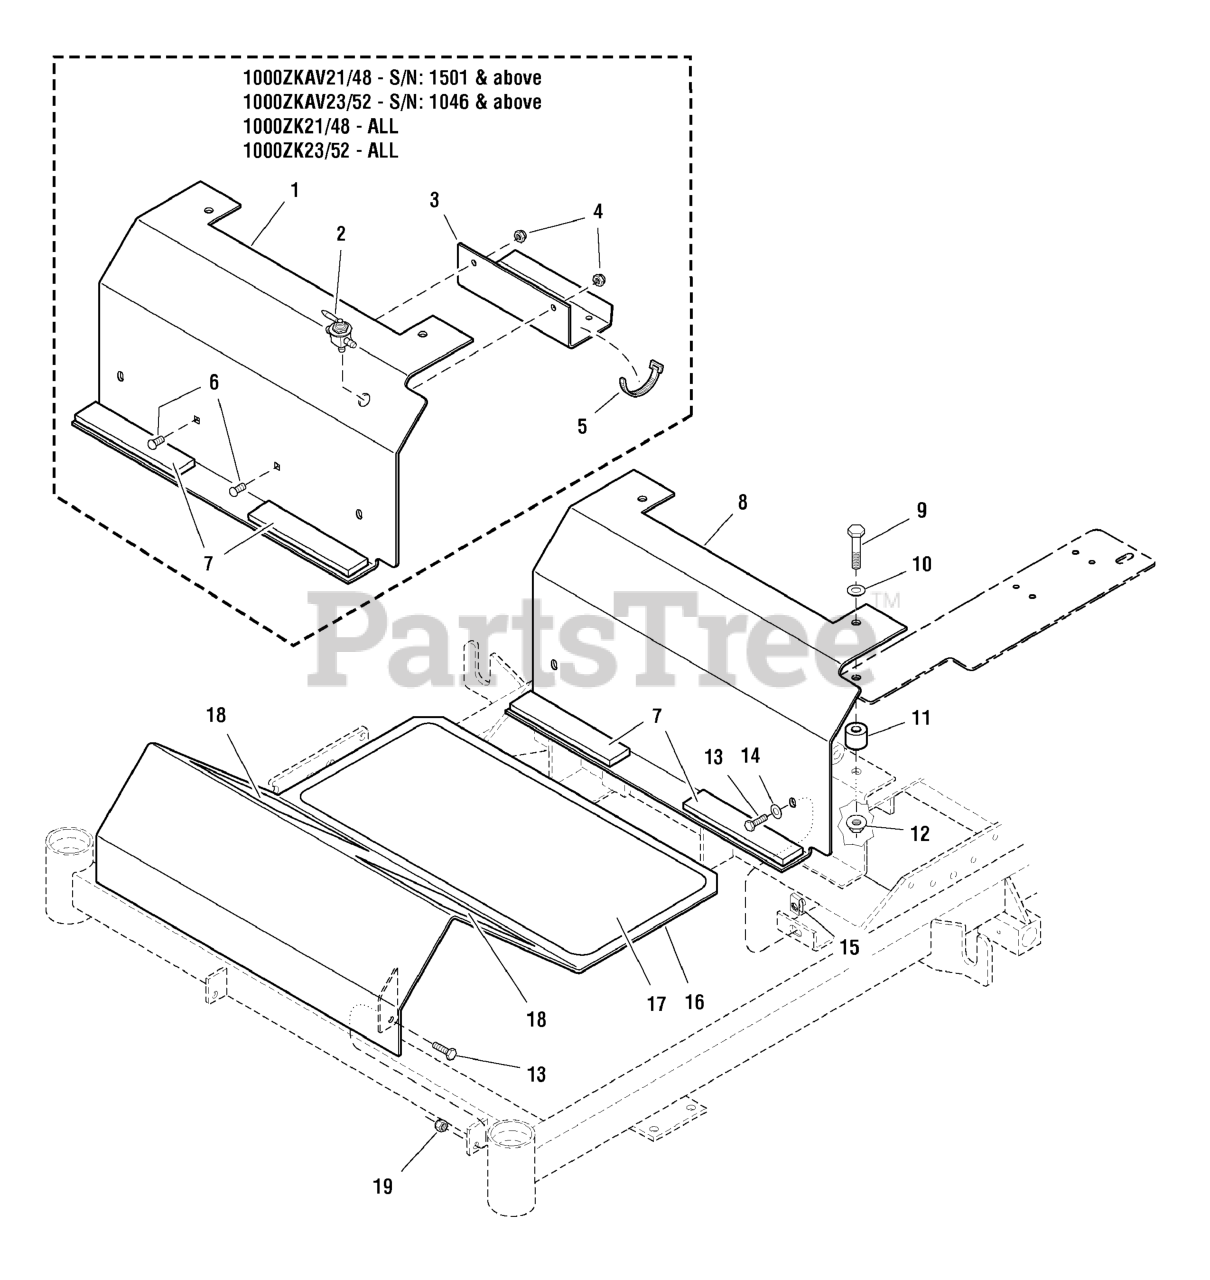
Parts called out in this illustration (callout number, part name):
19	SPRING, COMPRESSION
20	HHCS, 1/4-20 X 0.625, GR5, ZINC/CLEAR
21	WASHER, 1/4 SAE
22	BRACKET, SWITCH MOUNT - RED
23	NUT, 1/4-20 HEX SERR. FLANGE
24	PLATE, NEUTRAL LOCK - RED
25	DAMPENER, CONTROL,#(P6709/P3610)
26	BALL STUD, 5/16 X .50,# PC-477-2)
27	BEARING, FLANGE
28	MOUNT, CONTROL ARM - BLK
29	ROD, HYDRO CONTROL, OUTFRONT
30	NUT, 3/8-16 HEX NYLON LOCK
31	BOLT, 5/16-18 X 1 GD5 YZ
32	WASHER, 5/16 LOCK CZ
33	BOLT, 3/8-16 X 1-1/4 SHCS
34	BOLT, 3/8-16 X 1-3/4" GD5 CZ
35	NUT, 5/16-18 HEX SERRATED FLANGE (SMALL)
36	NUT, 3/8-16 HEX NYLOCK FLANGE
37	BOLT, 5/16-18 X 2 GD5 TFL
